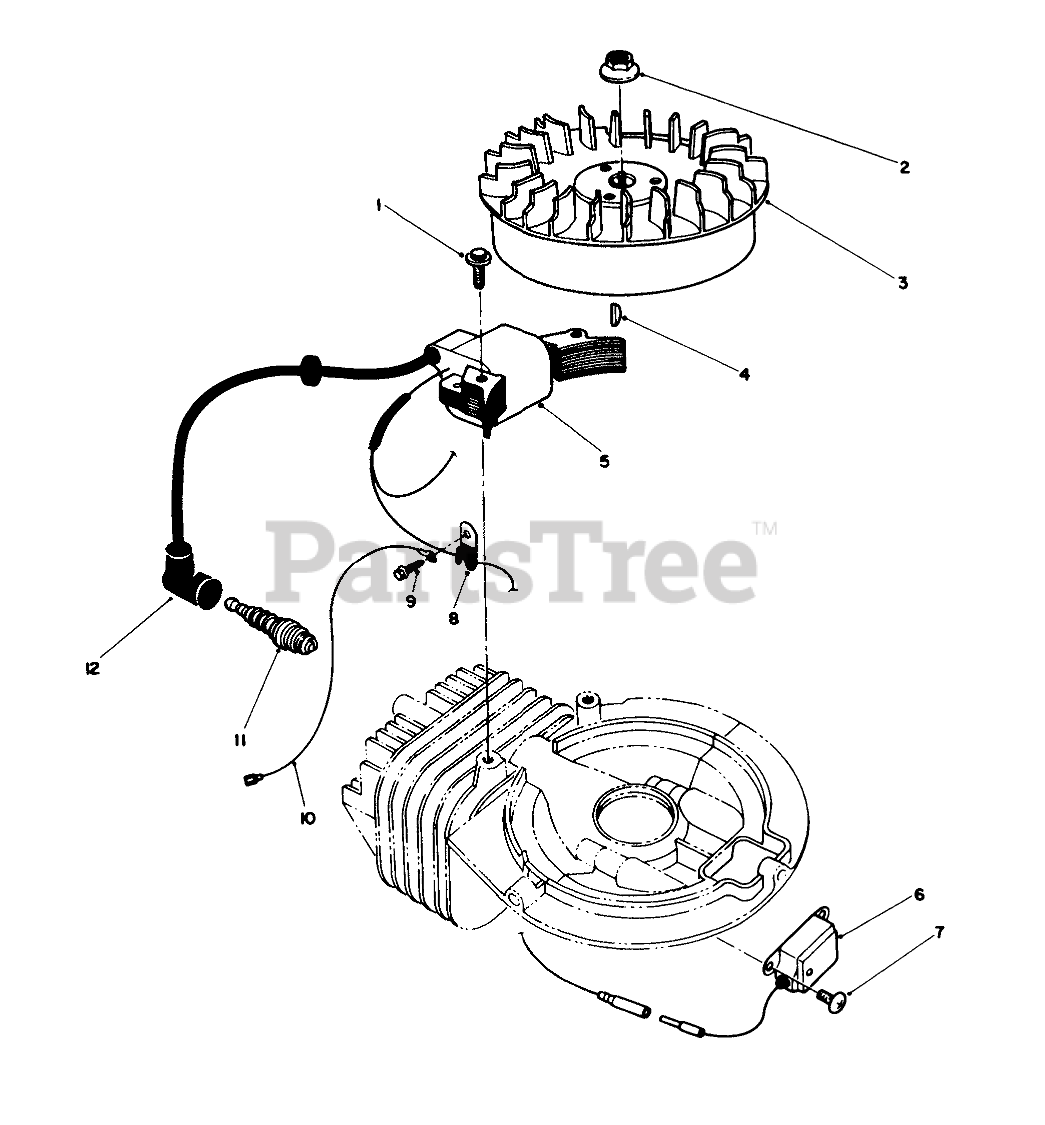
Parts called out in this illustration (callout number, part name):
1	SCREW
3	FLYWHEEL
5	MAGNETO COIL
6	MAGNETO MODULE
7	SCREW
8	CLAMP
11	Sparkplug
12	CAP-SPARKPLUG
